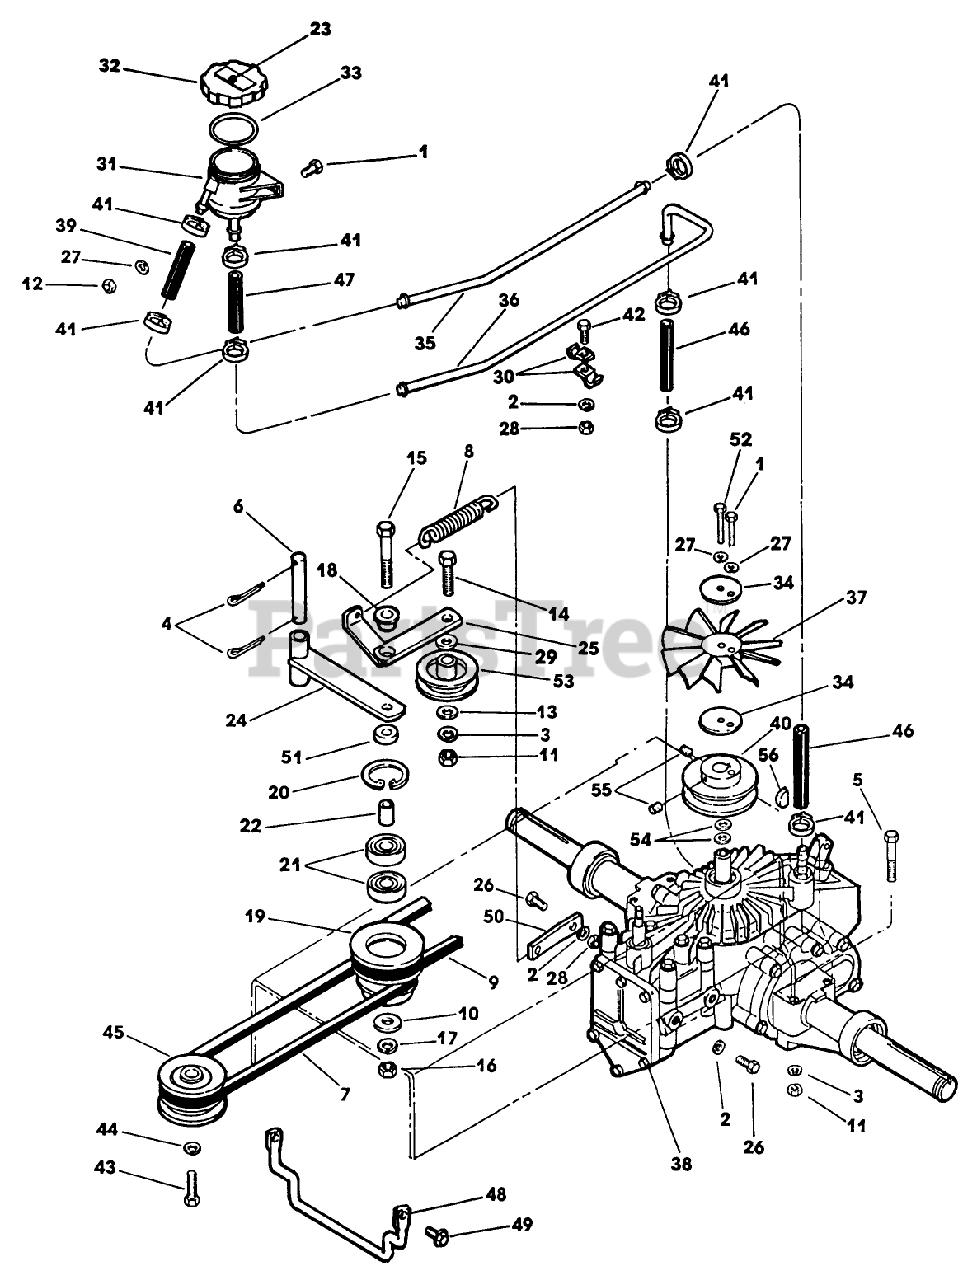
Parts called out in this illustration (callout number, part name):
3	WASHER
8	SPRING
9	V-BELT
10	SPACER
11	NUT
12	NUT
13	WASHER
18	SPACER
19	IDLER ASSEMBLY
24	IDLER ARM WELDMT *B
26	SCREW - HEX
28	NUT SS
33	GASKET,COVER
34	FRAME MTG WASHER LB
41	CLAMP, SNAP
